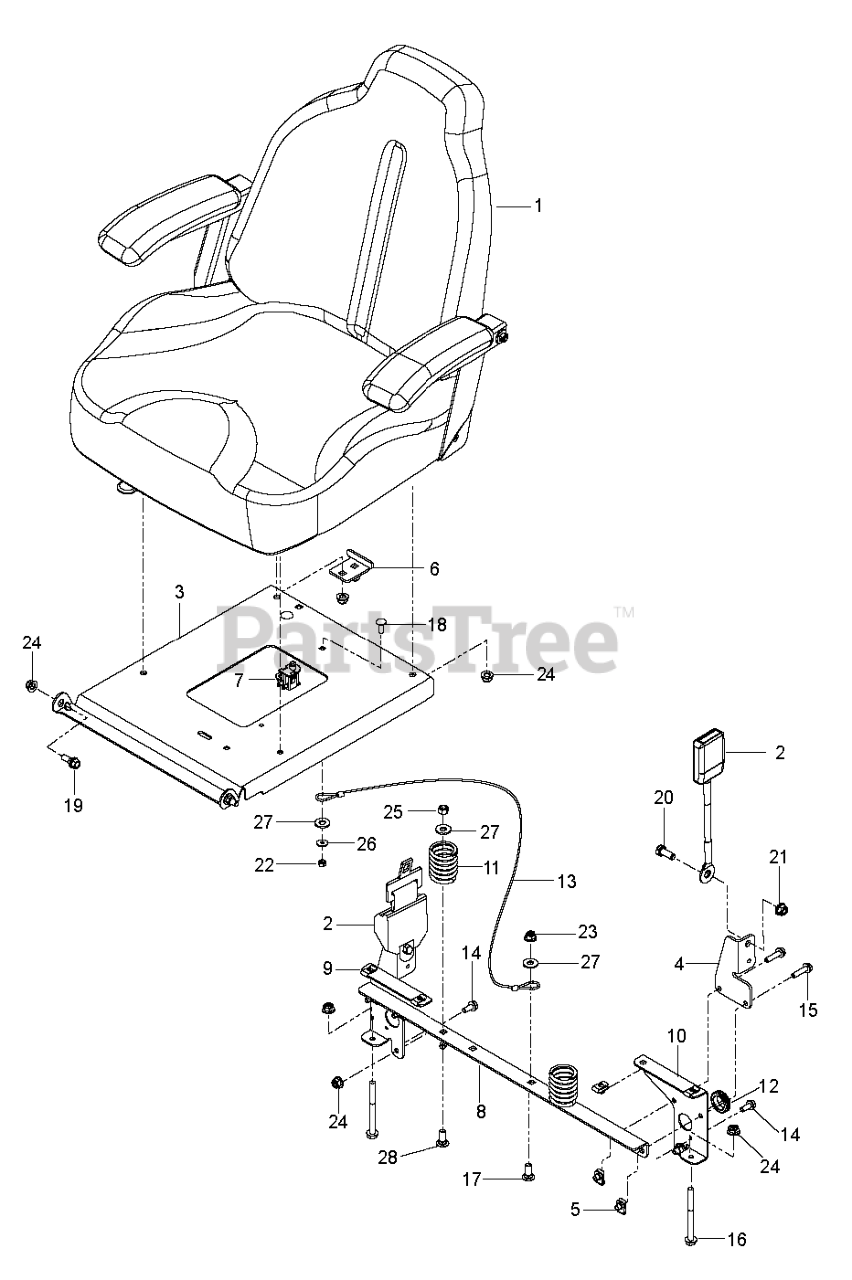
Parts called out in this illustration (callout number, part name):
1	SEAT.ASM.907.TRACK.W/BELT
2	SEAT BELT, RETRACTABLE
3	SUPPORT.SEAT.ORANGE
4	MOUNT.SEAT.BELT.BLACK
5	U-CLIP 5/16-18 NUT RETAINER
6	STOP SEAT BLACK
7	SWITCH.SNAPMOUNT.NC
8	SUPPORT.SEAT. BLK
9	SUPPORT.RT.BLK
10	SUPPORT.LT.BLK
11	SPRING.COMPRESSION.SEAT.BLACK
12	RUBBER GROMMET
13	SEAT LANYARD
14	HHFS 5/16-18 X 3/4
15	HHFS 5/16-18 X 1.25 TPBLT GD 5
16	BOLT.HEX.FLNG.5/16-18X3.75
17	RHSNB 3/8C X 1
18	1/4-20X3/4 CARR BLT
19	SB 5/16-18 HEX HD GD5, BLK ZN
20	SCREW 7/16-20 X 1 HHB GR5
21	NUT HEX 7/16F LOCK RP
22	NUT.1/4-20.HEX.NYLOC.ZD
23	NUT 3/8-16 NYLOC
24	5/16-18 NYLOC FLANGE NUT
25	NUT 3/8-16 HEX FLG NYLOC ZD
27	RP WASHER 3/8 FLAT
28	RHSNB 3/8C X 1
